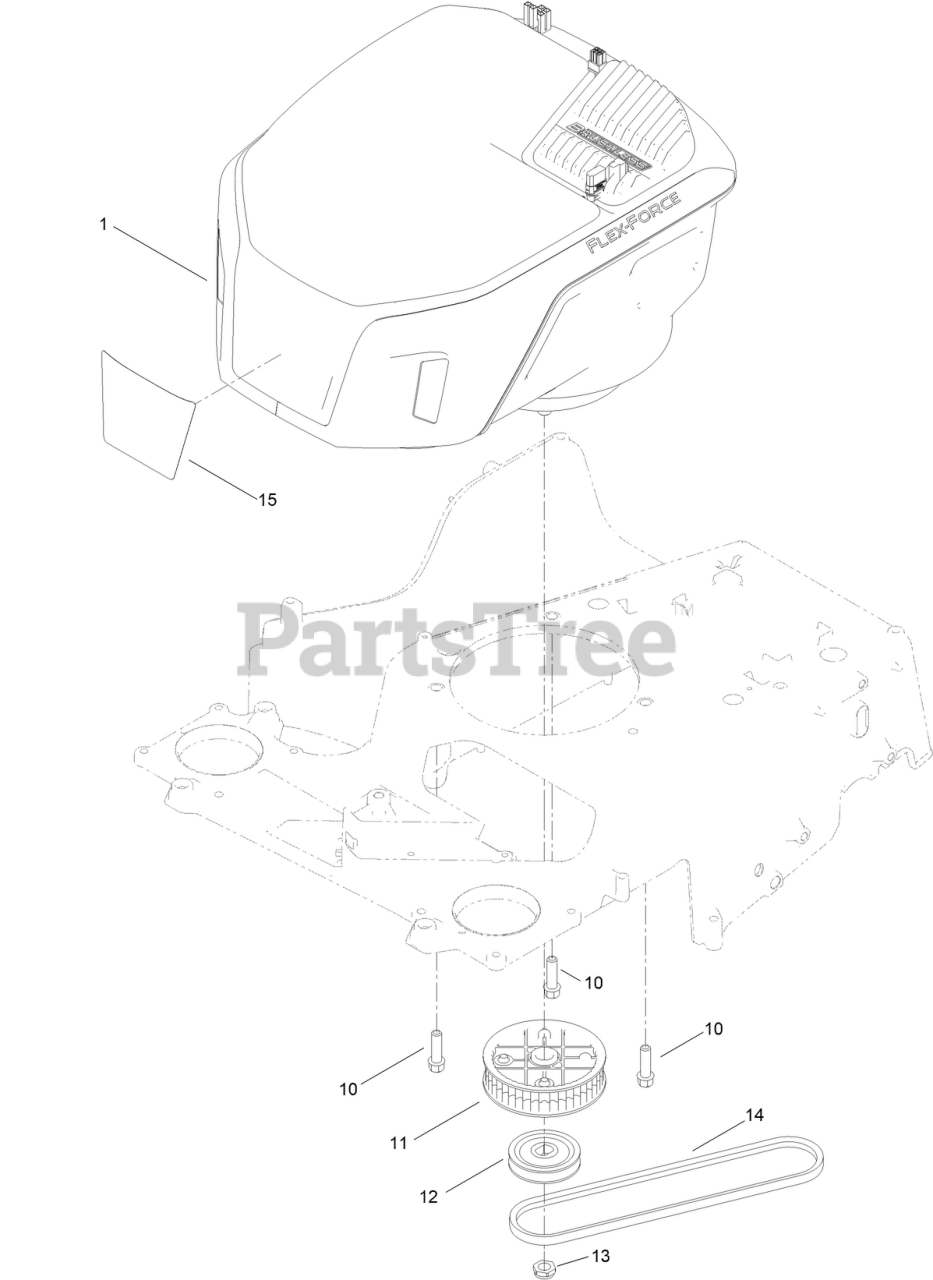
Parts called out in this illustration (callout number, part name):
1	MOTOR MODULE 60V
10	SCREW-THD FORM, HWH
11	SPROCKET
12	PULLEY-TRACTION
13	NUT-LOCK, NI
14	V-BELT, TRACTION
15	DECAL-60V
